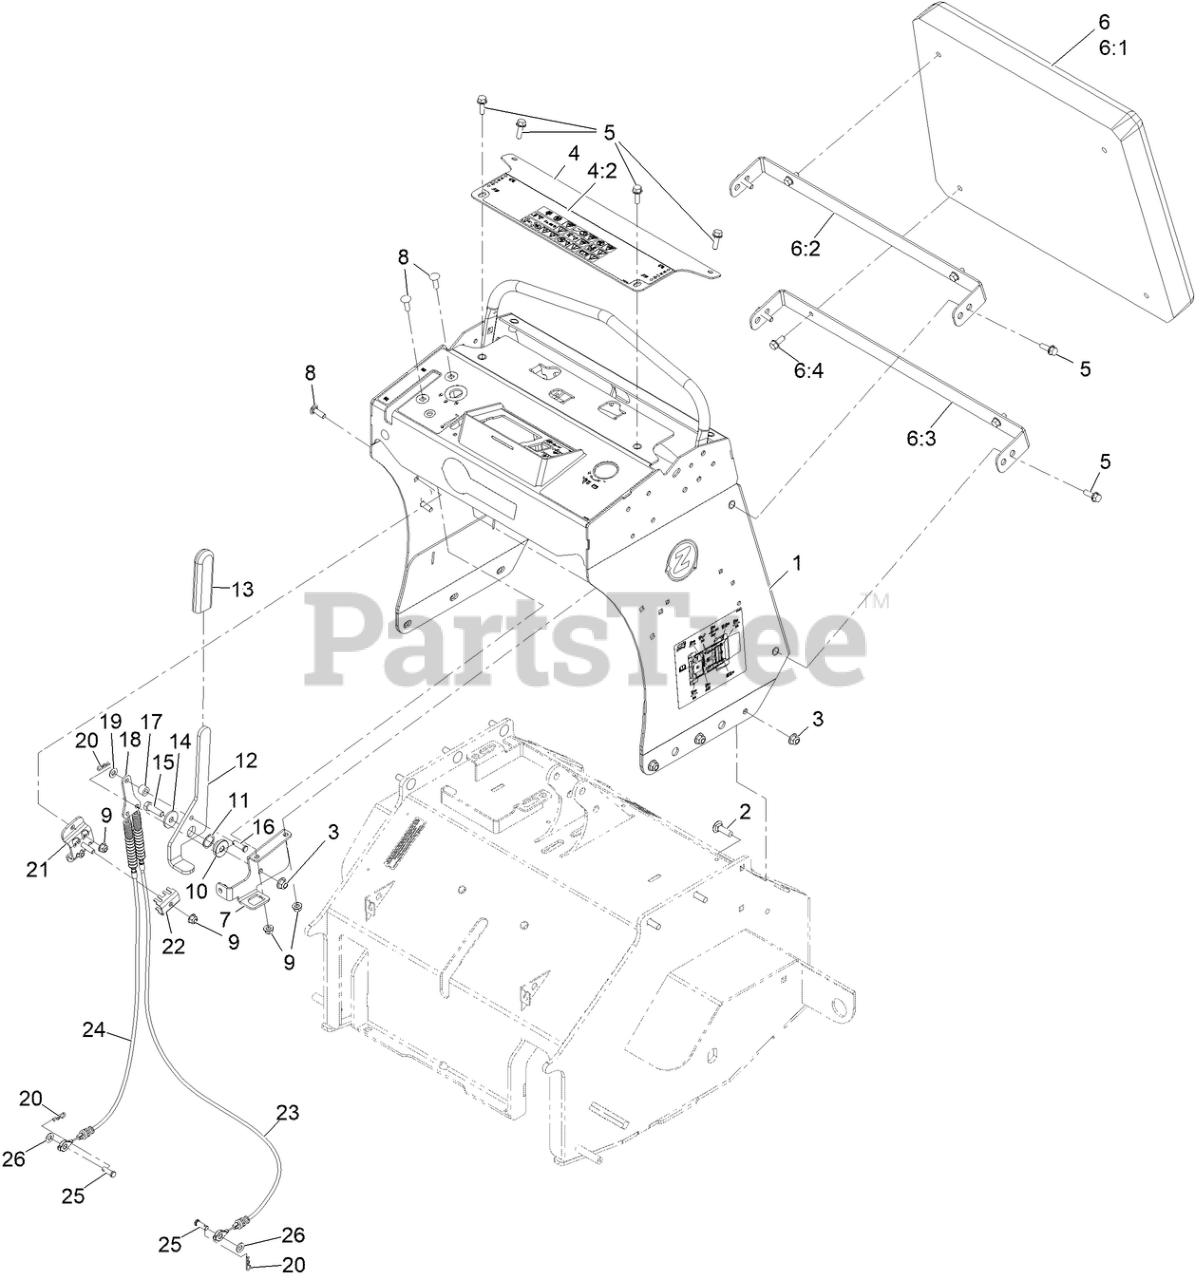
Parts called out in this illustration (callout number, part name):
1	CONTROL TOWER ASM
2	BOLT-CARR
3	NUT-HF, NI
4	CONTROL PANEL ASM
4:2	DECAL-WARNING
5	SCREW-HHF
6	Cushion ASM
6:1	CUSHION-GREY
6:2	BRACKET-PAD, UPPER
6:3	BRACKET-PAD, LOWER
6:4	SCREW-HHF
7	BRACKET-PIVOT, BRAKE
8	SCREW-CARR
9	NUT-HF, NI
10	PIVOT-FLANGE
11	WASHER-WAVE
12	HANDLE-BRAKE
13	GRIP-LEVER
14	WASHER
15	SCREW-HH
16	Pin-Yoke
17	Bushing
18	Yoke-Cable
19	SPACER-NYLON
21	Mount-Cable, Brake
22	Clamp-Cable
23	CABLE-BRAKE, LH
24	CABLE-BRAKE, RH
25	PIN-CLEVIS
26	WASHER-PLAIN
